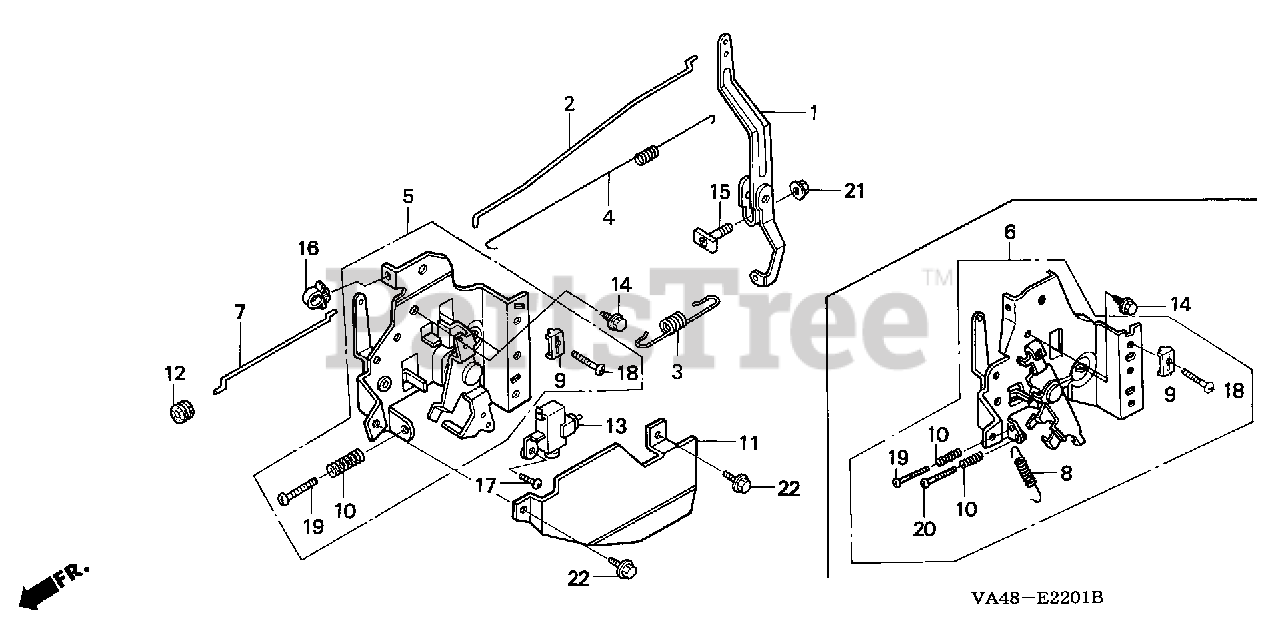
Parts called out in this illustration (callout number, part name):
1	ARM, GOVERNOR
2	ROD, GOVERNOR
3	SPRING, GOVERNOR (STD)
4	SPRING, THROTTLE RETURN
5	CONTROL ASSY.
5	CONTROL
6	CONTROL
7	ROD, CHOKE
8	SPRING, LEVER
9	HOLDER, CABLE
10	SPRING, CONTROL ADJUSTING Use from Engine SN 2327377.
11	PROTECTOR, CONTROL
12	GROMMET, CHOKE ROD
13	SWITCH ASSY., ENGINE STOP
14	BOLT, FLANGE (6X12) (CT200)
15	BOLT, GOVERNOR ARM
16	CLIP, WIRE HARNESS
17	SCREW, PAN (4X8)
18	SCREW, PAN (5X16)
19	SCREW, PAN (5X20)
20	SCREW, PAN (5X28)
21	NUT, FLANGE (6MM)
22	BOLT, FLANGE (6X10)
